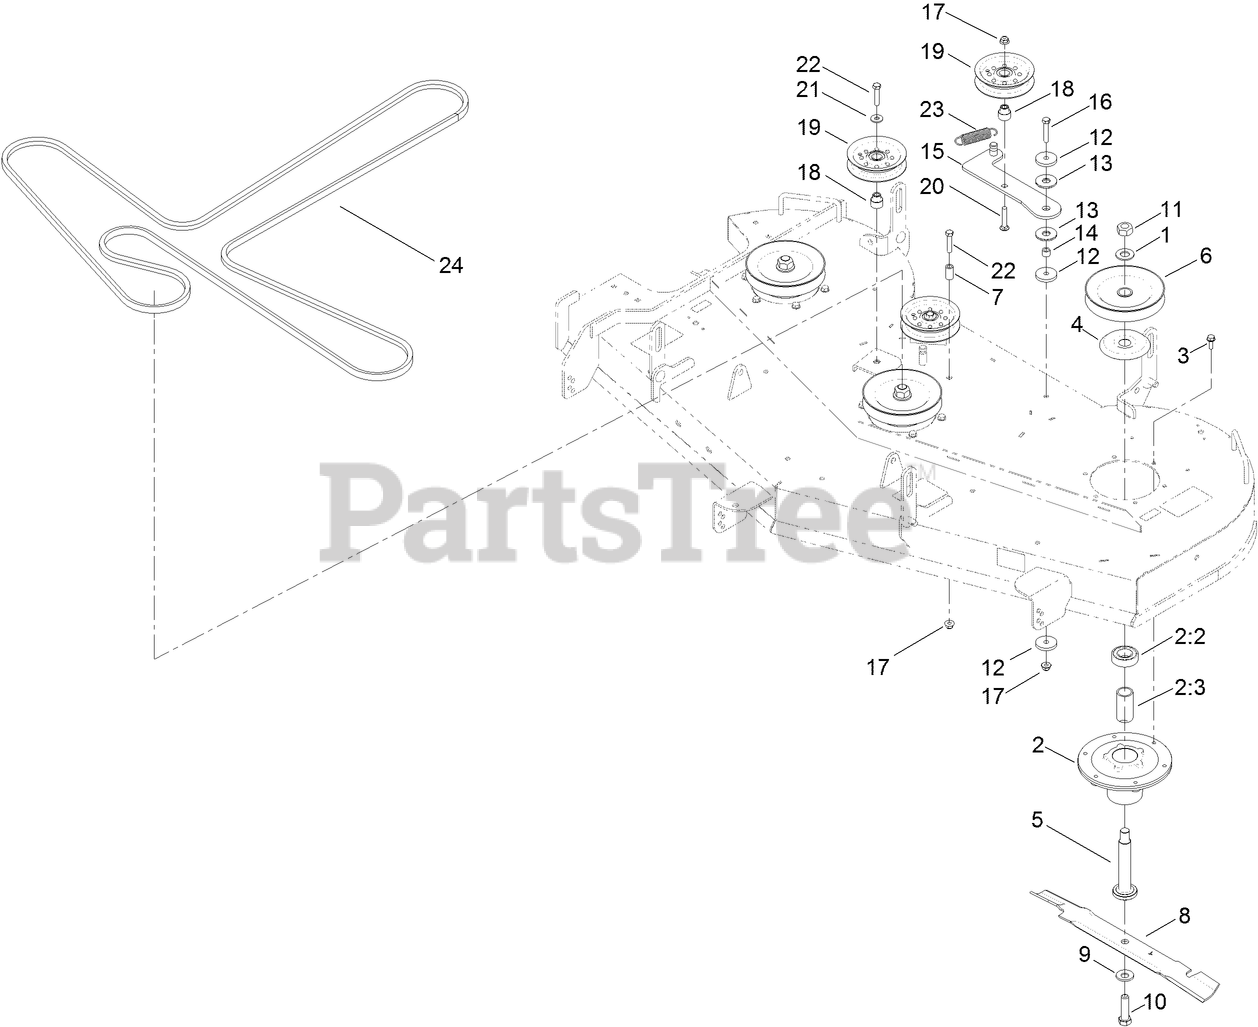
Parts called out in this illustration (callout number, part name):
1	WASHER
2	SPINDLE ASM
2:2	BEARING-BALL
2:3	SPACER-BEARING
3	SCREW-TAPTITE
4	SHIELD-BEARING
5	SHAFT-SPINDLE
6	PULLEY
7	SPACER
8	BLADE-HI FLOW, 20.5 INCH
9	WASHER-BELLEVILLE
10	SCREW-BLADE
11	NUT-HEX
12	WASHER-PLAIN
13	WASHER-FRICTION, COMPOSITE
14	BUSHING-LEVER, LIFT
15	ARM-IDLER
16	SCREW-HH
17	NUT-HF, NI
18	BUSHING-IDLER
20	SCREW-CARR
21	WASHER-HARDENED
22	SCREW-HH
23	SPRING-EXTENSION
